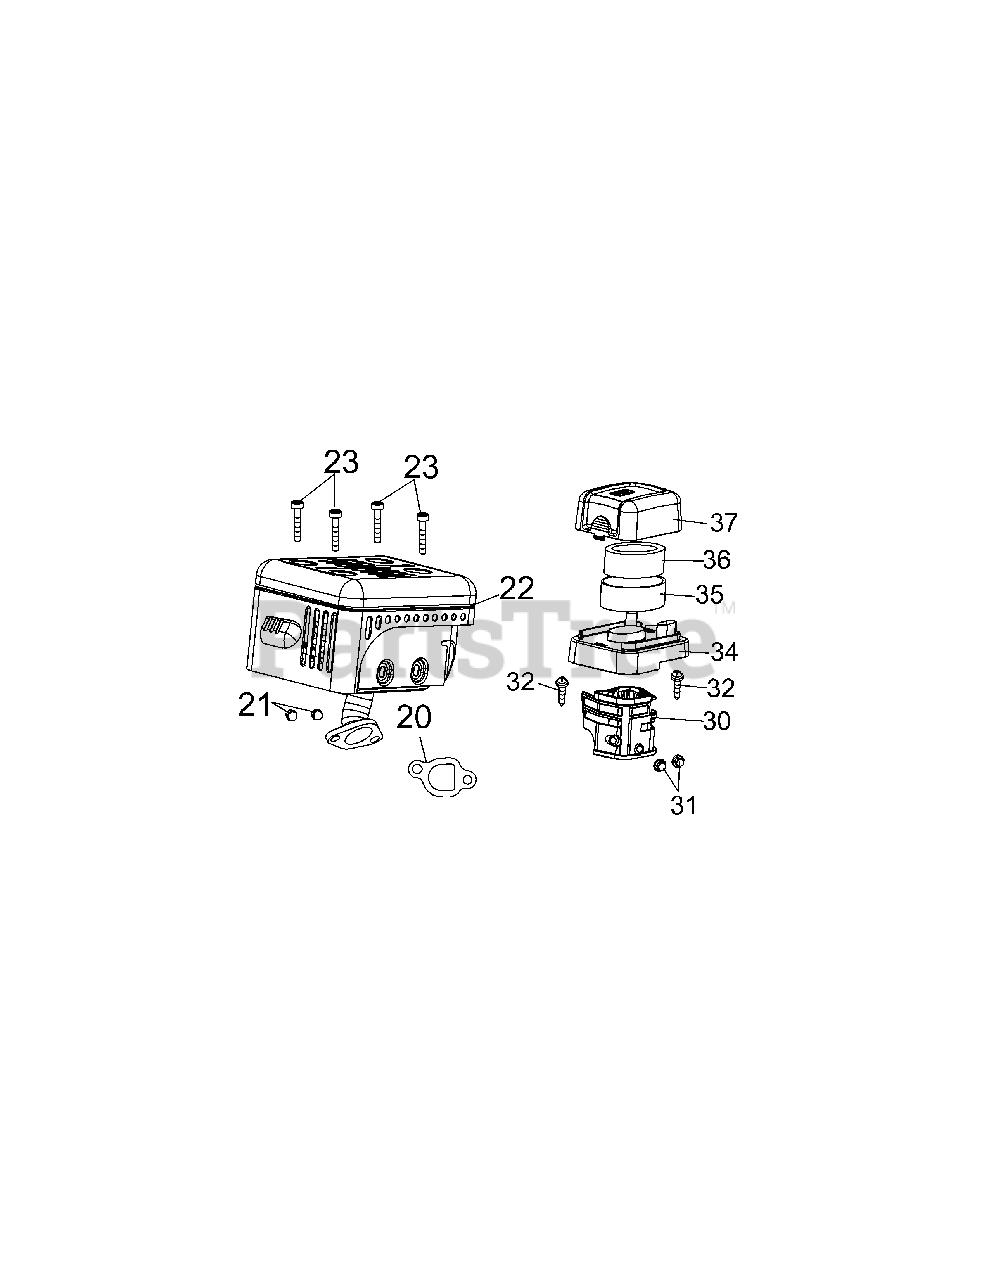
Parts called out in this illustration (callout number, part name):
20	Exhaust Pipe Gasket
22	Muffler Assembly
23	Bolt
30	Air Cleaner Housing
32	Self-Tapping Bolt M4.2×16
34	Silencer Plate
35	Air Cleaner Assembly
36	Air Cleaner Assembly
37	Air Cleaner Cover
